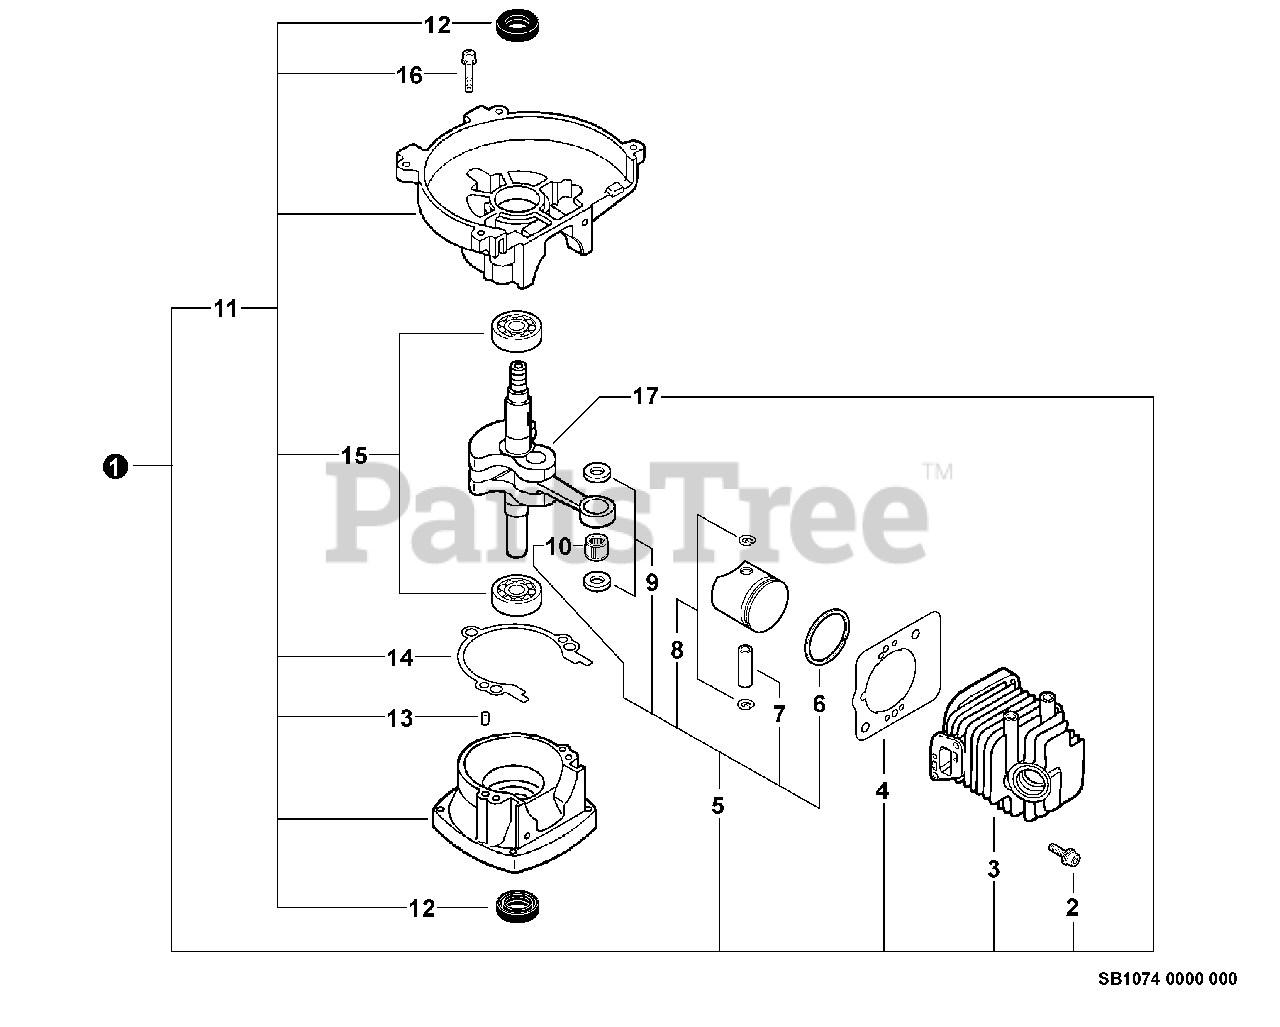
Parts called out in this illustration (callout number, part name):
1	SHORT BLOCK -- SB1074
2	SCREW - 5X22
3	CYLINDER
4	GASKET, CYLINDER
5	PISTON KIT
6	RING, PISTON
7	PIN, PISTON
8	RING, RETAINING
10	BEARING, NEEDLE - 8
11	CRANKCASE KIT
12	SEAL, OIL
13	PIN - LOCATING
14	GASKET, CRANKCASE
15	BEARING, BALL - 6201
16	SCREW - 5X28
17	CRANKSHAFT ASSY
